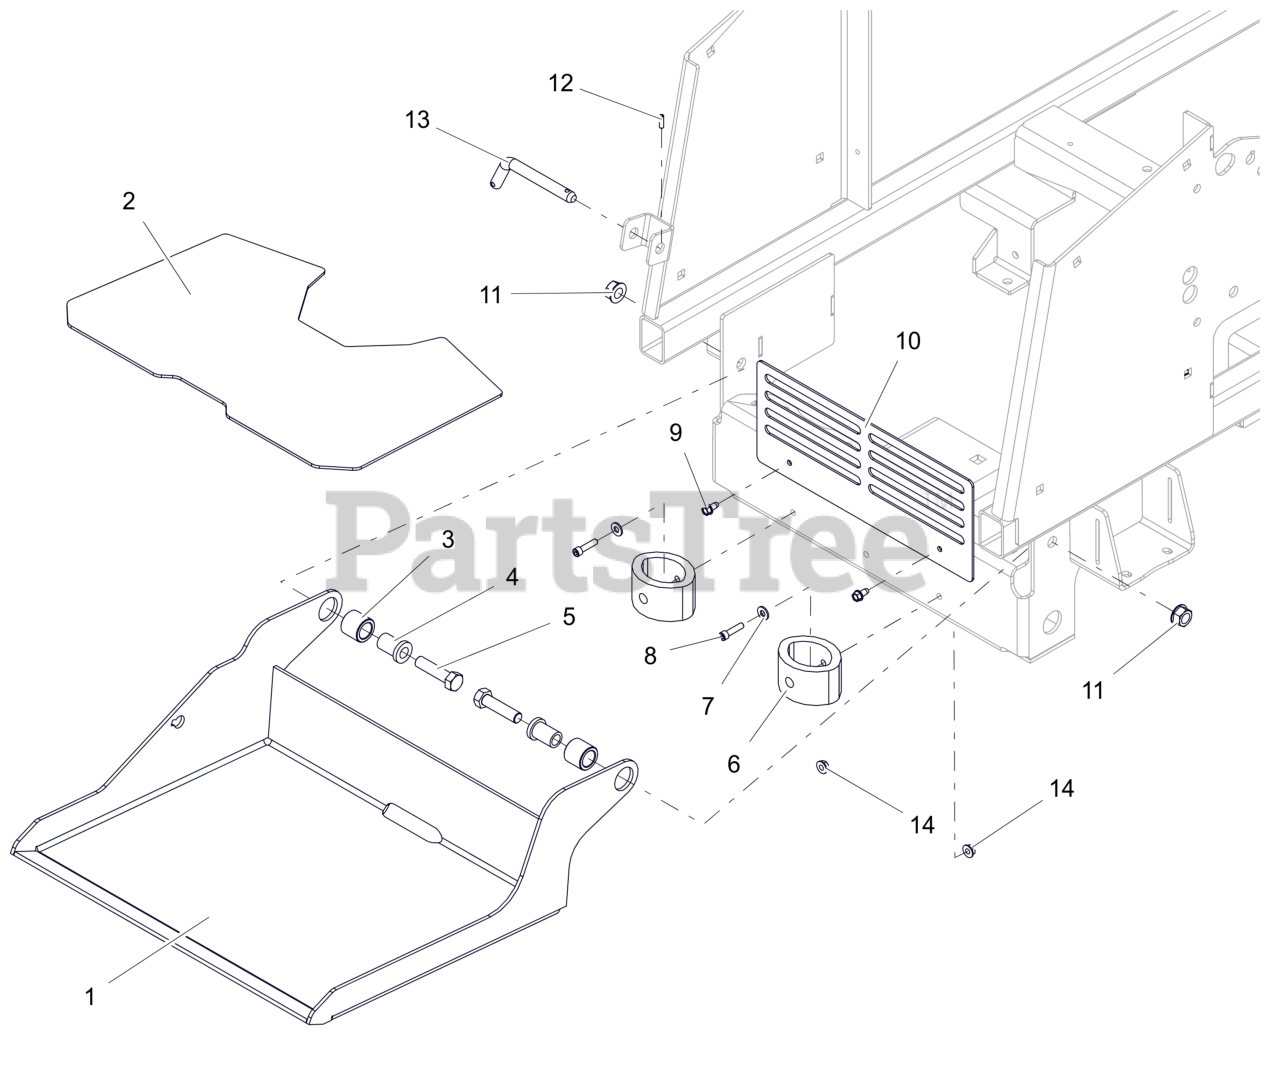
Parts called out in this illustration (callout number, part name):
1	PLATFORM, OPERATOR
2	TAPE, OPERATOR PLATFORM GRIP
3	SPCR, PIVOT
4	BSHG-FLG .515X.746X1.290X1.000
5	BLT, HEX .50-13X2.00 G5 ZCC
6	BUMPER, PLATFORM
7	WSHR,FLT .281X.625X.065 ZCC
8	SCR, SKH .25-20X1.00
9	SCR-TAP .25-20X.50 HWH ZCC
10	GUARD, FOOT (RED)
11	NUT-LK-CTR-FLG .500-13 GG ZCC
12	PIN-ROLL .188X.63
13	PIN- HOC SELECTOR
14	NUT-LK-CTR-FLG .25-20 ZC120
